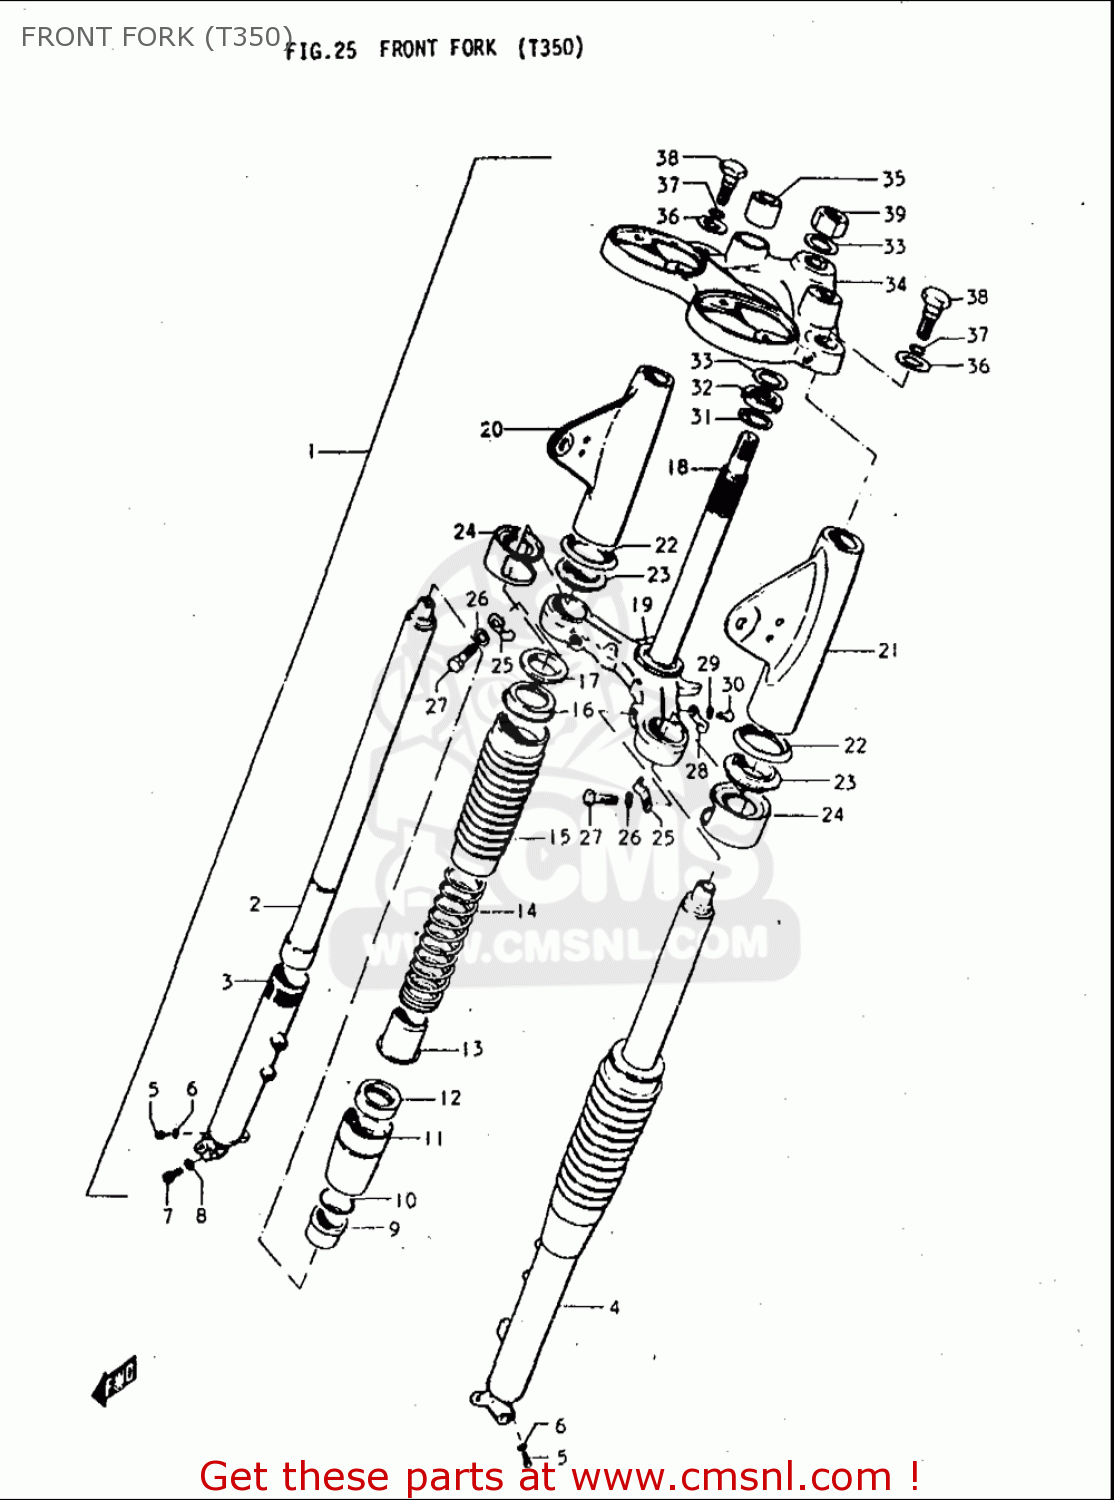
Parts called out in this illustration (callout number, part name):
5	OIL DRAIN PLUG
6	GASKET,DRAIN,PLUG (NAS)
8	WASHER,LOCK
12	SEAL,OIL
15	BOOT,SPRING COVER
22	SEAT,HEADLAMP BRACKET
23	CUSHION,HEADLAMP BRACKET
25	CLIP,SPEEDOMETER CABLE
26	WASHER,LOCK
28	CLIP,BRAKE CABLE
29	WASHER,LOCK
36	WASHER
38	CAP,FORK INNER TUBE
39	NUT
